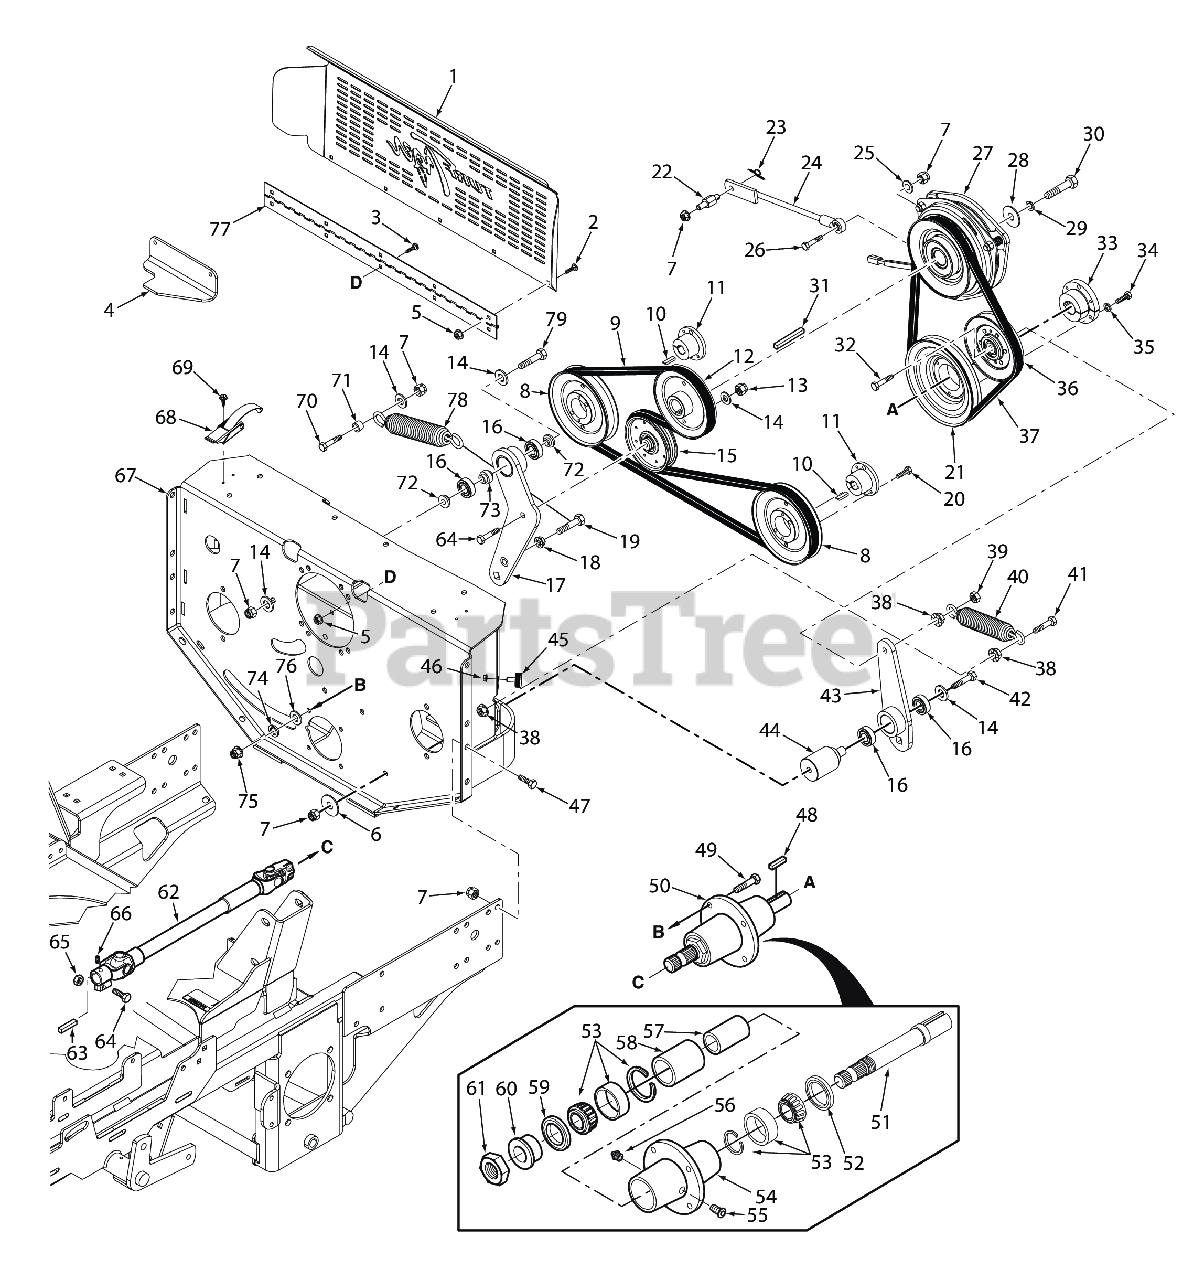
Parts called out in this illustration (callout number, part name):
1	Cover, Rear
2	Bolt, Carriage 1/4-20 x 1/2"
3	Serr. Fl. Hex Head CPSCR, 1/4-20 x 3/4"
4	Bracket, Idler Stop
5	NUT, 1/4-20 SERRATED FLANGE HEX HEAD
6	Flatwasher, 3/8" Special (.391 x .938 x .105)
7	HEX NUT, ELASTIC STOP LOCK, 3/8-16
8	Pulley, 5.75 O.D. (Gasoline Engines)
8	Pulley, 6.35 O.D. (Diesel Engine)
9	Belt, STTII Pump Drive (Gasoline Engines)
9	Belt, STTII Pump Drive (Diesel Engine)
10	Key, 5mm x 5mm x 30mm
11	Tapered Hub, 17mm Bore
12	Pulley, 5.67 O.D. (Kawasaki & Kohler Only)
12	Pulley, 5.67 O.D. (35BV & 37BV-EFI Only)
12	Pulley, 5.67 Dia. - 1.125 Bore - Kubota
13	Bolt, Hex Head 3/8-16 x 1" Ser. Flg.
14	Flatwasher, 3/8 (.391 x .938 x .105 HD) Grade 8
15	Pulley, Idler 4� Dia.
16	BEARINGS, BALL, NEUTRAL RETURN
17	Idler Arm Assy.
18	Nut, Hex Serrated Flange 1/2-13
19	Bolt, Hex Head 1/2-13 x 2� Grd 8
20	Bolt, Hex Head 1/4-20 x 1" Grade 8 Black
21	Pulley, 6.70" O.D. Tapered Bore
22	Stud, Anti-Rotation
23	Pin, Rue Cotter 3/8" Diameter
24	Rod Assembly, Clutch Anti-Rotation
25	Flatwasher, 3/8-.438 x 1.00 x .083
26	Bolt, Hex Head 3/8-16 x 1-1/4", Kawasaki FX / FS
27	Electric Clutch w/Tag - GT-3.5 (FX850)
27	Clutch Assembly, GT3.5 (Diesel Engine)
27	Electric Clutch w/Tag - GT-5 (ECV860, ECV940)
28	Flatwasher, 7/16-.469 x 1.75 x .25 (48, 52)
29	Lockwasher, 7/16� Spring
30	Bolt, Hex Head 7/16-20 x 2-1/2" (Kohler)
30	Bolt, Hex Head 7/16-20 x 2-1/4" w/Patch (Kawasaki)
30	Bolt, Hex Head M10-1.5 x 50 (Kawasaki)
31	Key, 1/4 x 1/4 x 3-1/4�
32	Bolt, Hex Head 3/8-16 x 2-1/2" 1.5 Thread Grd.8
33	Tapered Hub, 1.00 Bore
34	BOLT, HEX HEAD, 1/4-20 X 1-3/8(FULL THREAD)
35	Lockwasher, 1/4� Spring
36	IDLER PULLEY, "V" GROOVE
37	Belt, Pump Drive - Kubota
38	NUT, 3/8-16 SERRATED FLANGE HEX HEAD
39	Bolt, Hex Head 3/8-16 x 1" Ser. Flg.
40	Spring, PTO (Gasoline Engines)
40	Spring, PTO (Diesel Engine)
41	Bolt, Hex Head 3/8-16 x 1-1/2" Grade 8 Black
42	Bolt, Hex Head 3/8-16 x 4-1/2" Grade 8 Black
43	Idler Arm Weldment, PTO Drive
44	Pivot, Idler - PTO
45	Bumper, Rubber 5/16-18 x 5/8"
46	Nut, Serrated Flange 5/16-18 (Right Front Engine Mounting, Briggs and Kohler Only)
47	Bolt, Hex Head, 3/8-16 x 1 Gr. 5
48	KEY 1/4 X 1/4 X 1 1/2"(FOR 1" CRANKSHAFT
49	Bolt, Hex Head 5/16-18 x 1-3/4" Grade 8
50	Spindle Assembly, Deck Drive
51	Shaft, Deck Drive
52	SEAL, 2.00 O.D. X 1.50 BORE
53	Tapered Bearing Set (Two Bearings W/Race)
54	Housing, Spindle
55	RELIEF FITTING, TAPERED BEARING SPINDLE
56	GREASE FITTING, STR. 1/4-28 SELF TAP.
57	SLEEVE, CUTTER SPINDLE
58	Spacer, Outside, Cutter Spindle
59	Seal, 2.00" O.D. x 1.625" Bore
60	SPINDLE BUSHING, BOTTOM
61	Nut , Spec ial 1 -1/ 1 6 - 1 8
62	Driveshaft (Liquid-Cooled Engine & 35BVAC)
63	Key, 1/4" x 1/4" x 1" Clutch Mtg.
64	Bolt, Hex Head 3/8-16 x 1-3/4" (Kohler EFI)
65	Bolt, Hex Head 3/8-16 x 1" Ser. Flg.
66	Set Screw, 3/8-16 x 1/2" Internal Hex
67	Pump Mounting Plate Weldment (Gasoline)
67	Pump Mounting Plate Weldment (Diesel)
68	LATCH, HOOD
69	Screw, #10-32 x .563 Shakeproof
70	Bolt, Hex Head, 3/8-16 x 1-1/2"
71	Spacer, Spring Anchor
72	Spacer, Controls
73	Spacer, Bearing
74	Lockwasher, 5/16 (.317 x .586 x .078) Helical Spring
75	Lock Nut, 5/16-18 Elastic Stop Grade 8
76	Flatwasher, 5/16-.375 x .875 x .083 (35BV & 37BV-EFI)
77	Hinge, Rear Belt Guard
78	Spring, PTO (Gasoline Engines)
79	Capscrew, Hex Head 3/8-16 x 2.75"
